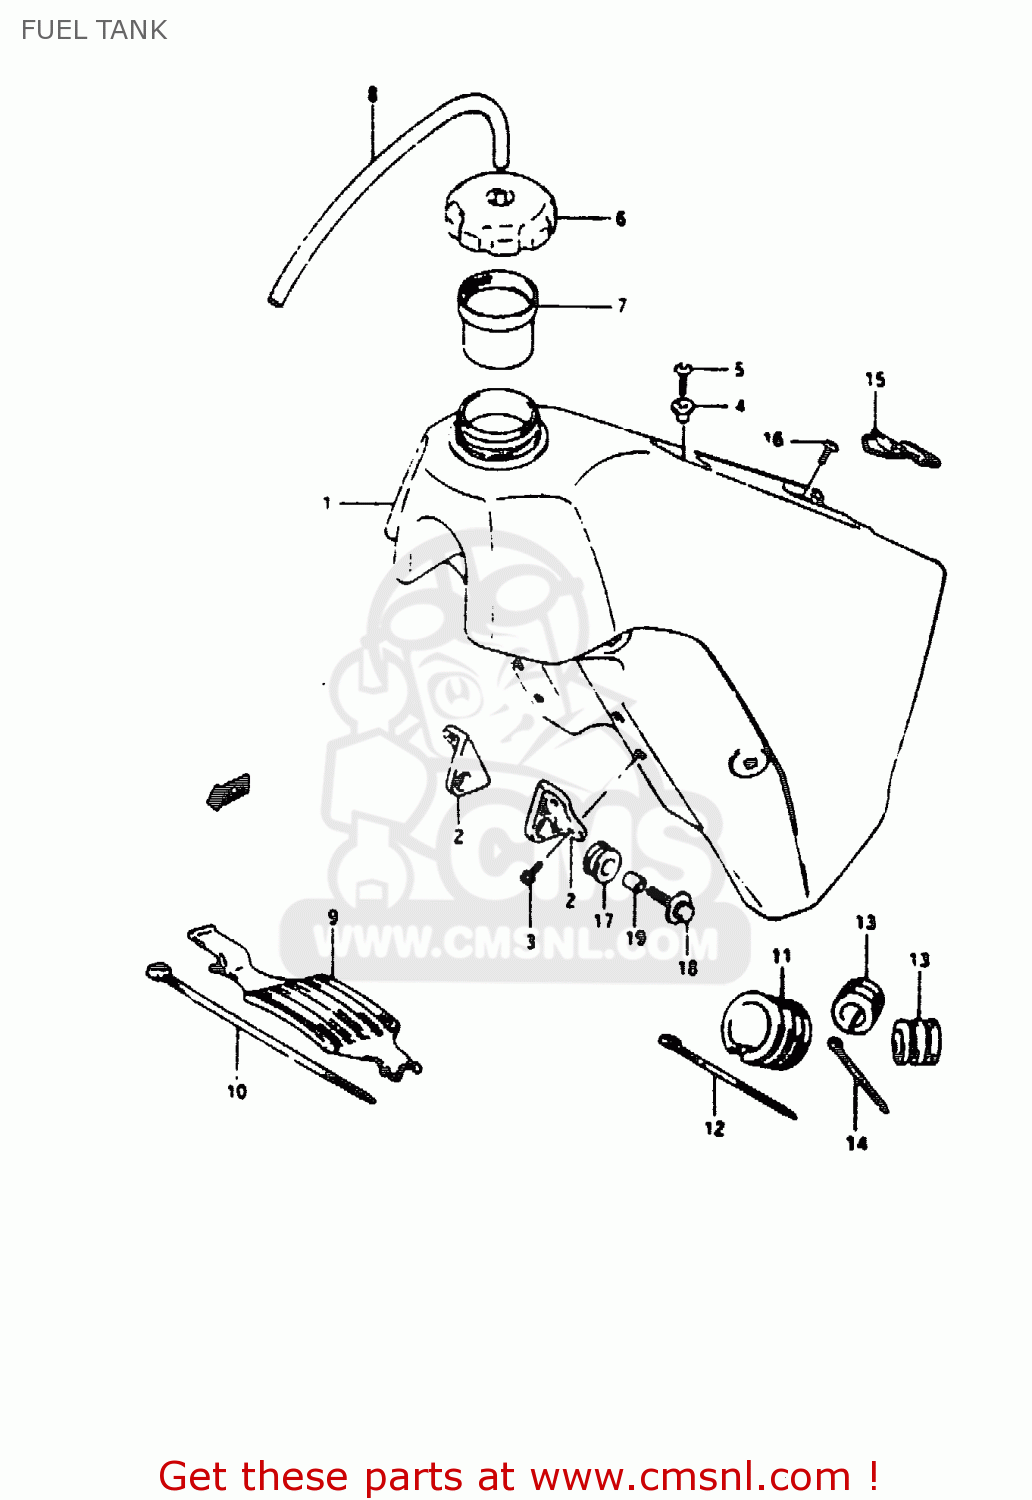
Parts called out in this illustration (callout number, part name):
1	TANK ASSEMBLY,FUEL
2	BRACKET,FUEL TANK FR
3	BOLT
4	HOOK,SEAT,FRONT
5	SCREW
6	CAP ASSY,FUEL TANK
7	TUBE,FILLER INLET
8	HOSE (L:600 280)
9	CUSHION,FUEL TANK NO.1
10	CLAMP
11	CUSHION,FUEL TANK NO.2
12	CLAMP(L:300)
13	CUSHION,FUEL TANK NO.1
14	CLAMP(L:145)
15	BAND,FUEL TANK RR
16	SCREW
17	CUSHION
18	BOLT(8X30)
19	SPACER (8.8X12X13.5)
